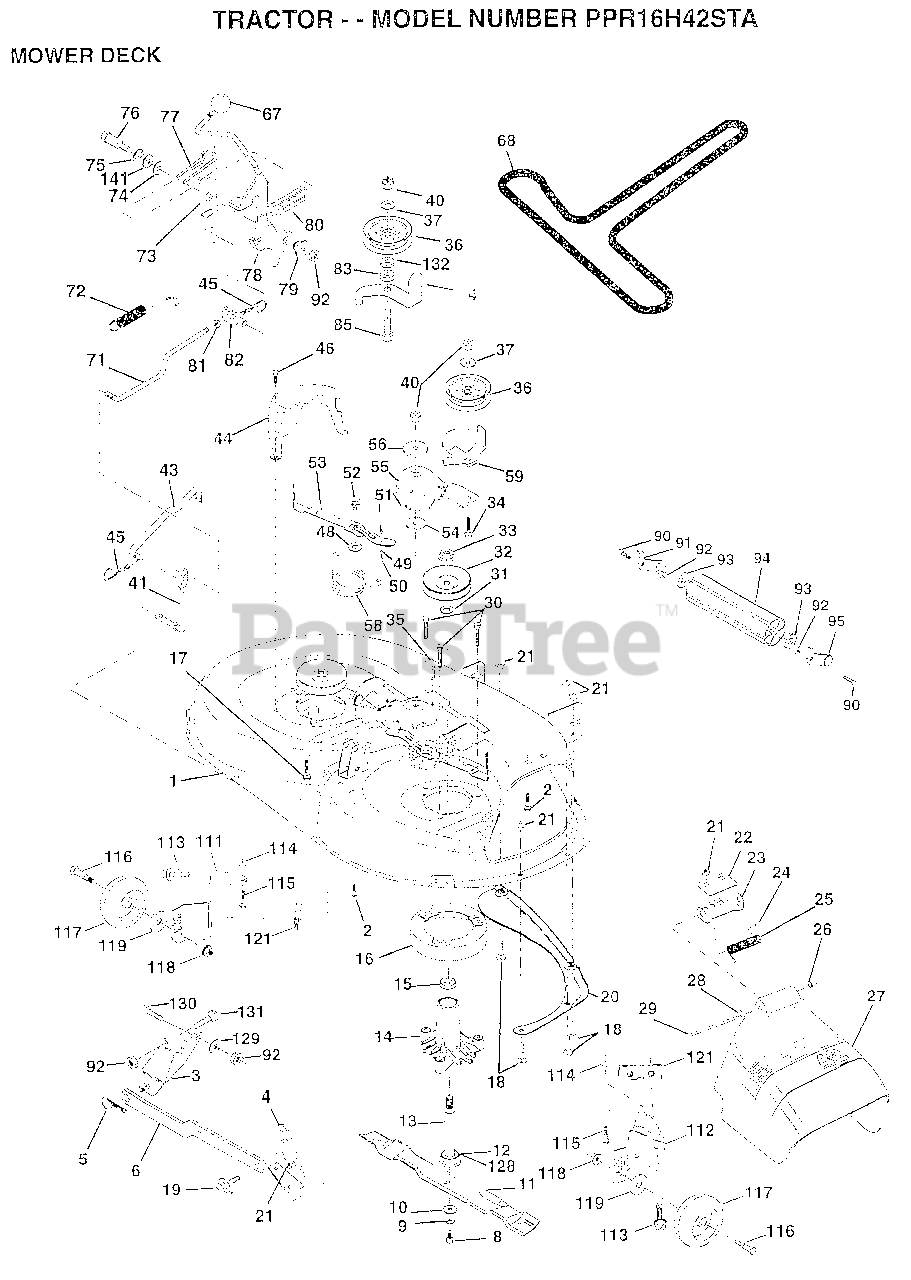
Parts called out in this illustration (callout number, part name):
1	"HOUSING ASSY.42"""
2	BOLT
3	BRKT ASM SWAY BAR
4	BRKT DECK SW BAR
8	BLADE BOLT
10	WASHER.HARD.BLADE
11	"BLADE.42"" HIPERF"
12	BEARING.BALL
14	HSG ASM MANDREL
15	BEARING
16	STRIPPER RND MWR
17	BOLT RDHD 3/8-16
18	BOLT
19	BOLT SHD 5/16-18
20	BAFFLE VORTEX 42
22	STIFFENER BRKT
23	DEFLECTOR BRKT
24	CAP-SLEEVE LT
25	SPRING TORSION
26	NUT PUSH M
27	DEFLECTOR.SHIELD
28	WASHER
29	HINGE ROD
30	"SCREW-THD ROLL,WA"
31	WASHER
32	PULLEY.MANDREL.42
34	BOLT
35	XMAS TREE FASTNER
36	FLAT IDLER PULLEY
37	WASHER
41	PIVOT ROD
43	ROD CLUTCH W/NIBS
44	GUARD MAND LH BLK
45	RETAINER M
46	SCREW.1/4-20X5/8
48	HARD SMALL WASHER
49	ROLLER ASM-CAM
50	SHOULDER BOLT
51	LOCKNUT
52	BOLT.SHLD.5/16-18
53	BRAKE PAD ARM ASM
54	HARDENED WASHER
55	ARM-IDLER
56	SPACER RETAINER
58	SPRING TORSN BRAK
59	GUARD IDLER TUV
67	KNOB.RD.7/16-14
68	BELT.V.T-PATH
71	ROD CLUTCH 38/42
72	RETURN SPRING
73	CLUTCH ARM SECOND
74	WASHER
75	RING
76	SHOULDER BOLT
77	SPRING KEEPER
78	LEVER.ASM.CLUTCH
79	BUSHING
80	SPRING.CLUTCH.MWR
81	TRUNION ADJ
82	NUT
83	WASHER
84	"KEEPER-BELT,FIXED"
85	BOLT
90	BOLT
92	NUT
93	WASHER
111	BRACKET.GWHL.LH.
112	BRACKET.GWHL.RH.
113	SCREW
116	BOLT M
117	WHEEL.GUAGE
118	LOCKNUT
119	WASHER
121	BRACKET.EXTRD.GWL
128	WASHER.FELT.
129	WASHER
130	BOLT
132	WASHER GT
141	WASHER .T
